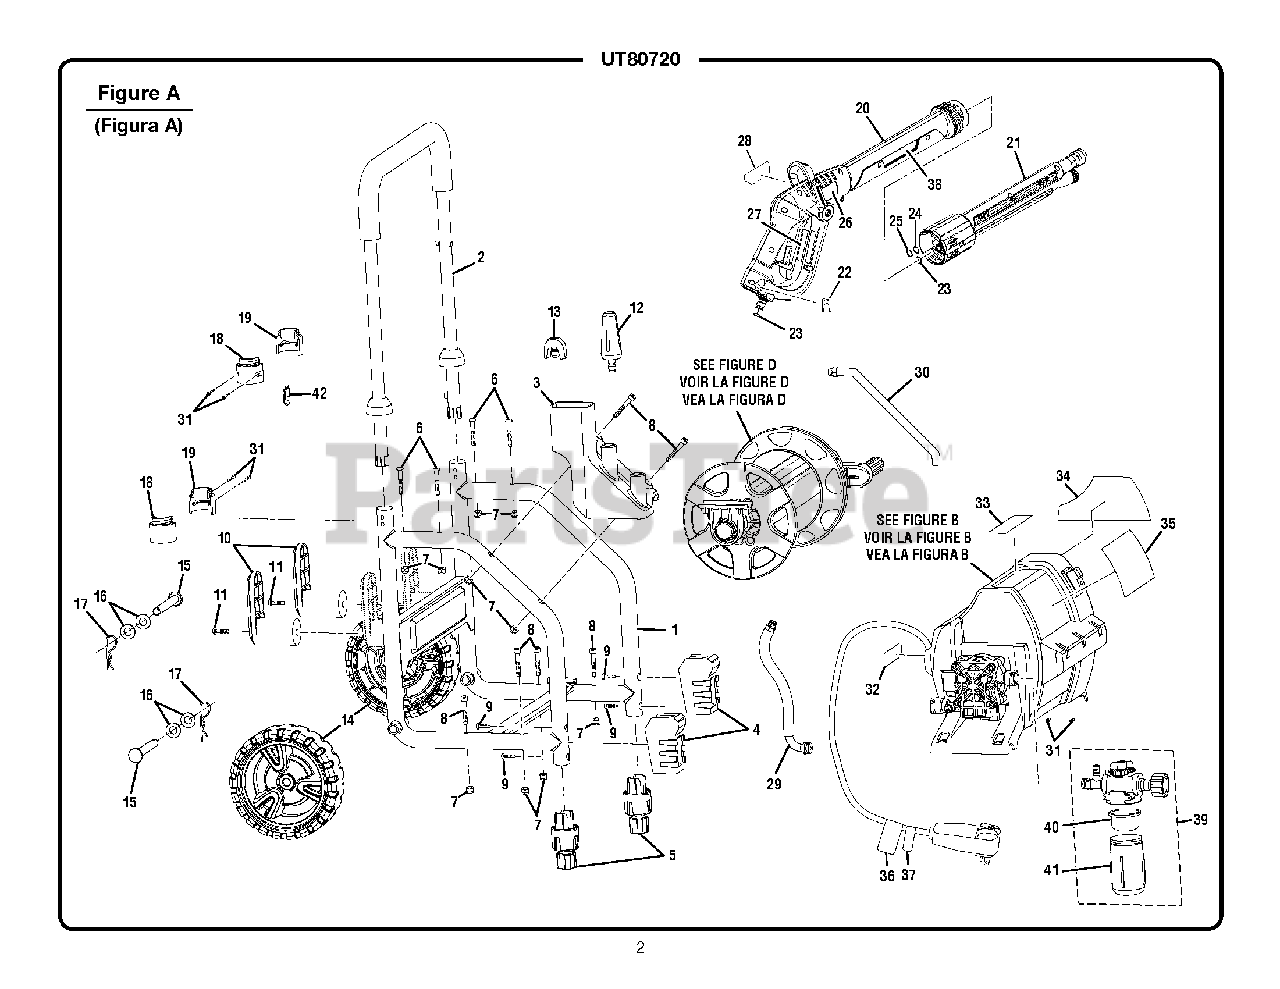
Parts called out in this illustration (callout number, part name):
1	Frame Assembly
2	Handle Assembly
3	Trigger Handle Holder
4	Foot Cover
5	Foot Assembly
6	Bolt (M6 x 40 mm, Pan Hd.)
7	Lock Nut (M6)
8	Screw (M6 x 40 mm)
9	Screw (M4 x 12 mm)
10	Cord Wrap Arm
11	Bolt (M8 x 20 mm, Hex Soc. Hd.)
12	Turbo Nozzle
13	Spray Nozzle (15deg)
14	Wheel Assembly
15	Wheel Axle
16	Washer (ID12.5 x OD24 x 2t)
17	Hitch Pin
18	Inner Handle Clamp
19	Outer Handle Clamp
20	Trigger Handle Assembly
21	Lance Assembly
22	High Pressure Hose Clip
25	Backup Ring
26	Logo Label
27	Trigger Rating Label
28	Warning Label
29	High Pressure Hose
30	Low Pressure Hose
31	Screw (M3 x 10 mm)
32	Data Label
33	Hydrosurge Label
34	Danger Label
35	Performance Label
36	Warning Label (UL)
37	California Proposition 65 Label
38	Logo Label (Hydrosurge)
39	G-Clean Assembly
40	Water Inlet Filter
41	Detergent Container
42	Handle Release Button
